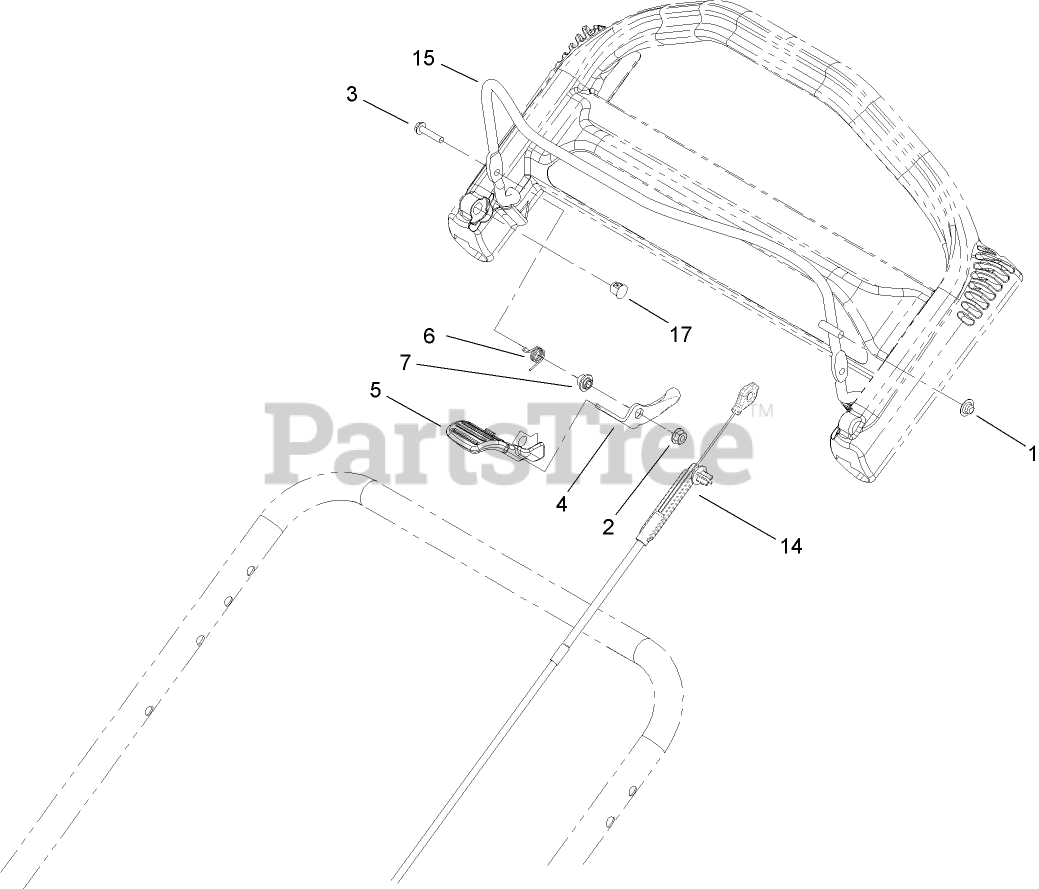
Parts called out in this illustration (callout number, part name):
1	NUT-SPEED
2	NUT-LOCK, FLANGE
3	SCREW-HWH
4	LEVER
6	SPRING-TORSION
7	SPACER
14	CABLE ASM
15	BAIL-BRAKE
17	PLUG-DOME
